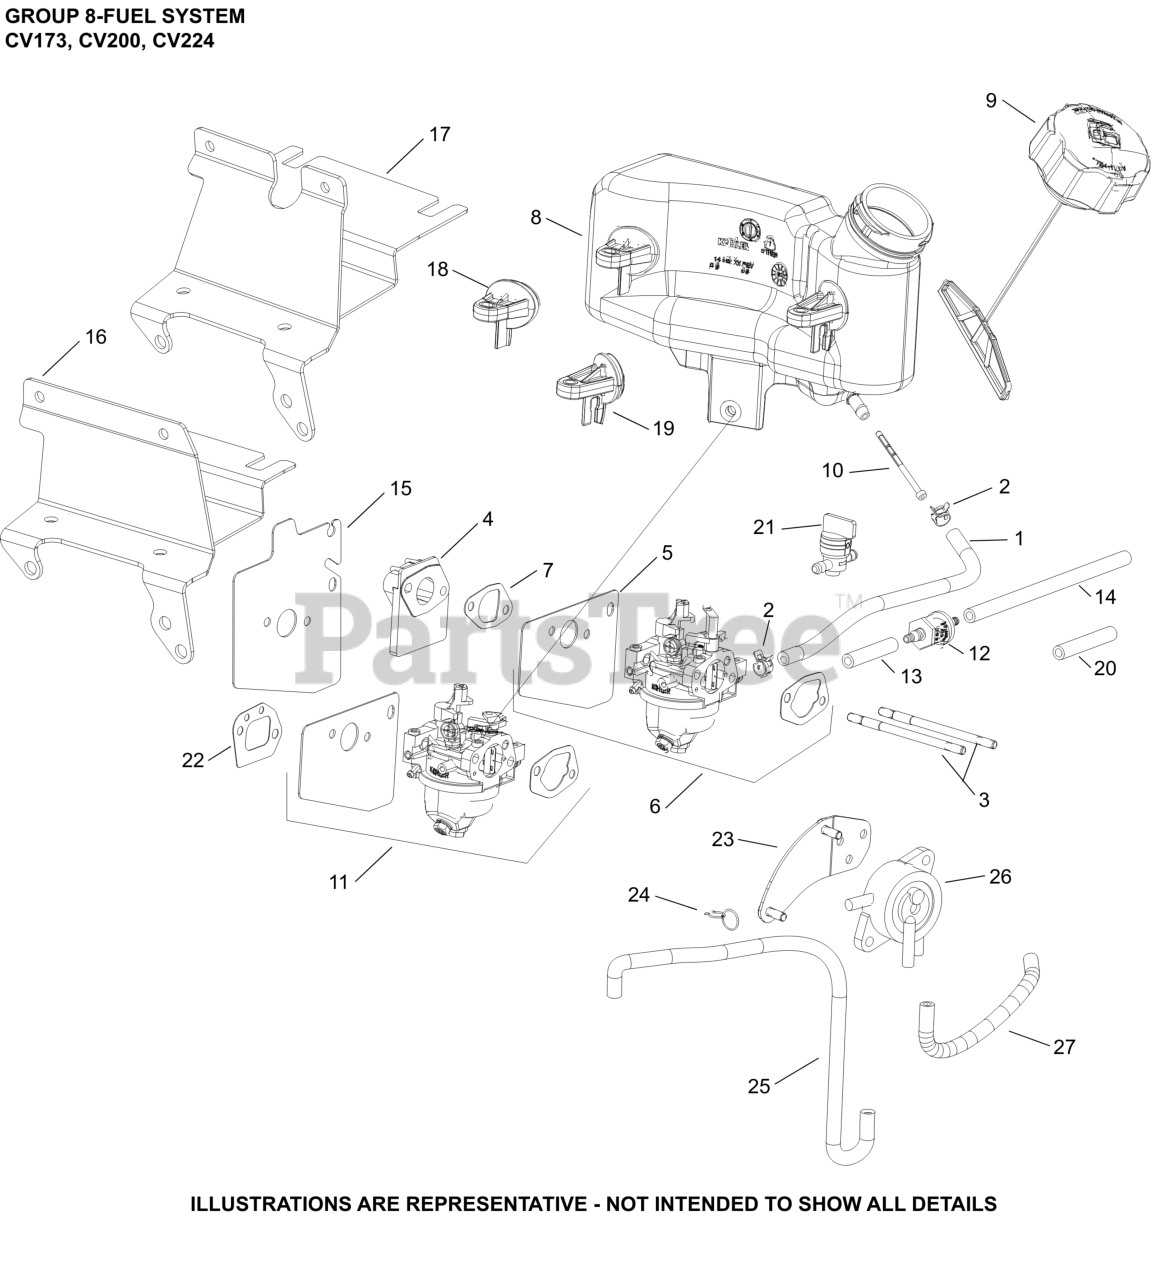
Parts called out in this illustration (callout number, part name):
1	HOSE, FUEL LOW-PERMEATION
2	CLAMP, HOSE (NON-CALIF)(#1423710S)
3	STUD,M6X1.0X100.2MM
4	KIT, SPACER
5	KIT, CARBURETOR HEAT SHIELD GASKET
7	KIT, INTAKE GASKET
8	TANK, FUEL
9	FUEL CAP ASSEMBLY
10	FILTER, FUEL IN-NIPPLE
11	KIT, CARBURETOR COMPLETE
NI	KIT, CARBURETOR REPAIR (RUIXING)
